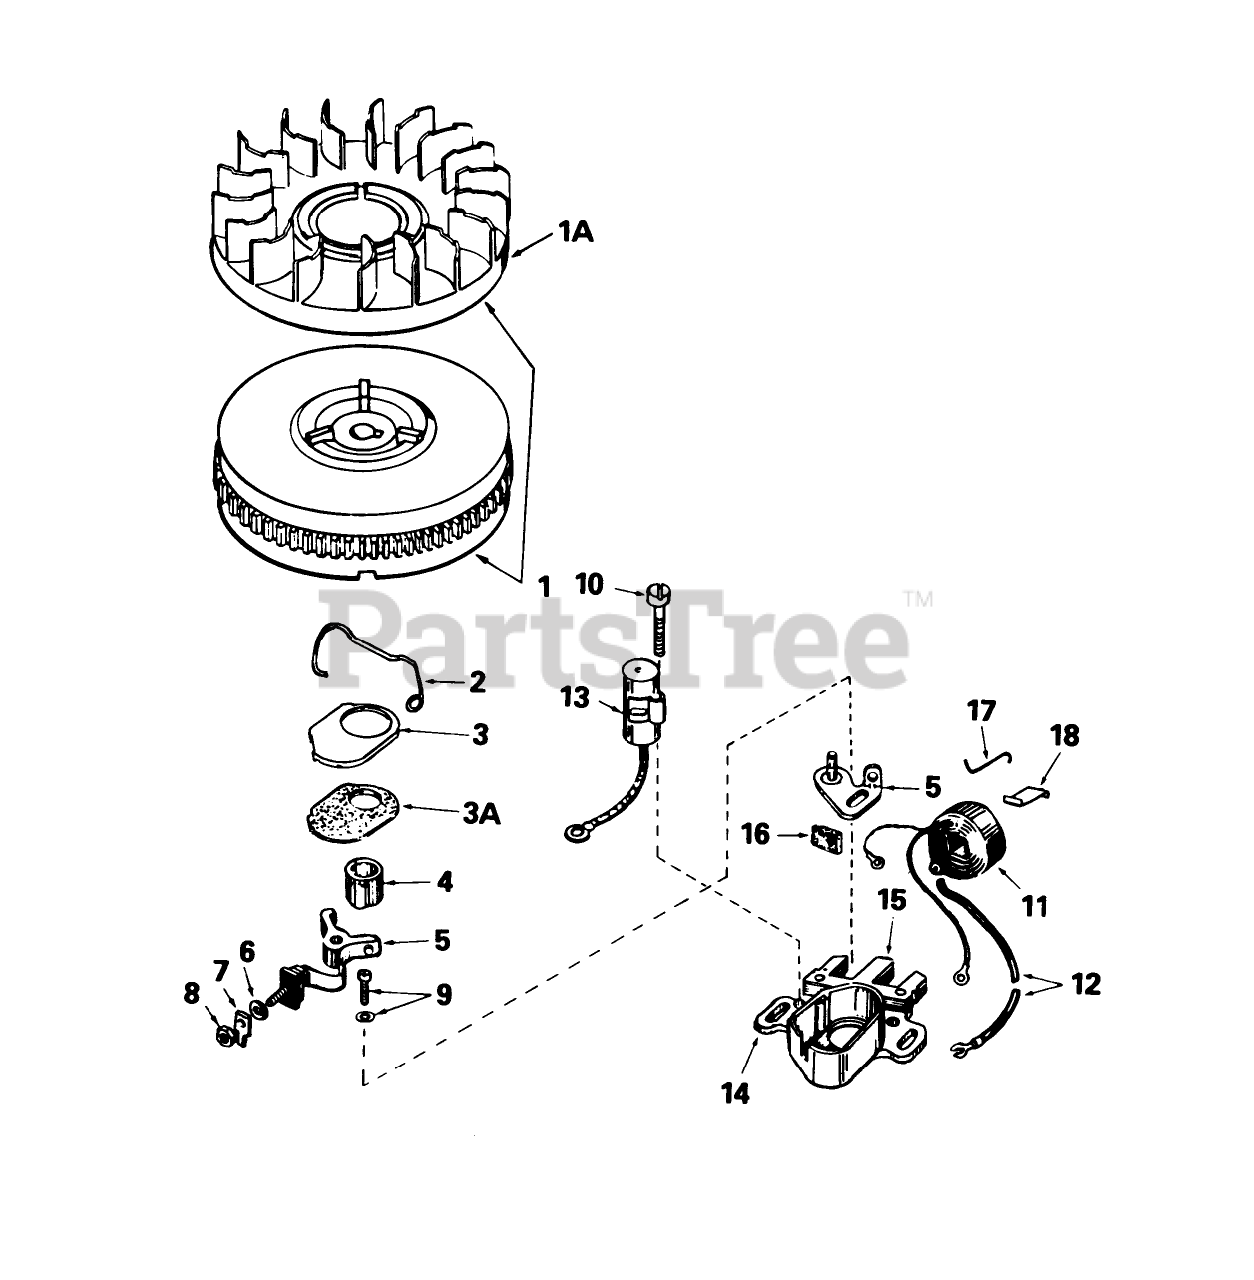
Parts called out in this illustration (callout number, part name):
1	Flywheel (Incl. Ref. #1A)
2	Spring Breaker Box
3	Cover-Dust
3A	Gasket-Dust Cover
4	Cam-Breaker
5	Breaker Assy.
6	Washer
7	Terminal, Ground
8	DECAL
9	Breaker Screw
10	Condenser Screw
11	Coil Assy. (Incl. No. 12)
12	Wire, Lead
13	Condenser
14	Core Plate
15	Stator Assy. (Incl. Ref. #2 thru 11, 13, 14, 16, 17 19)
16	Felt,Cam Wiper
17	Clip, Coil
